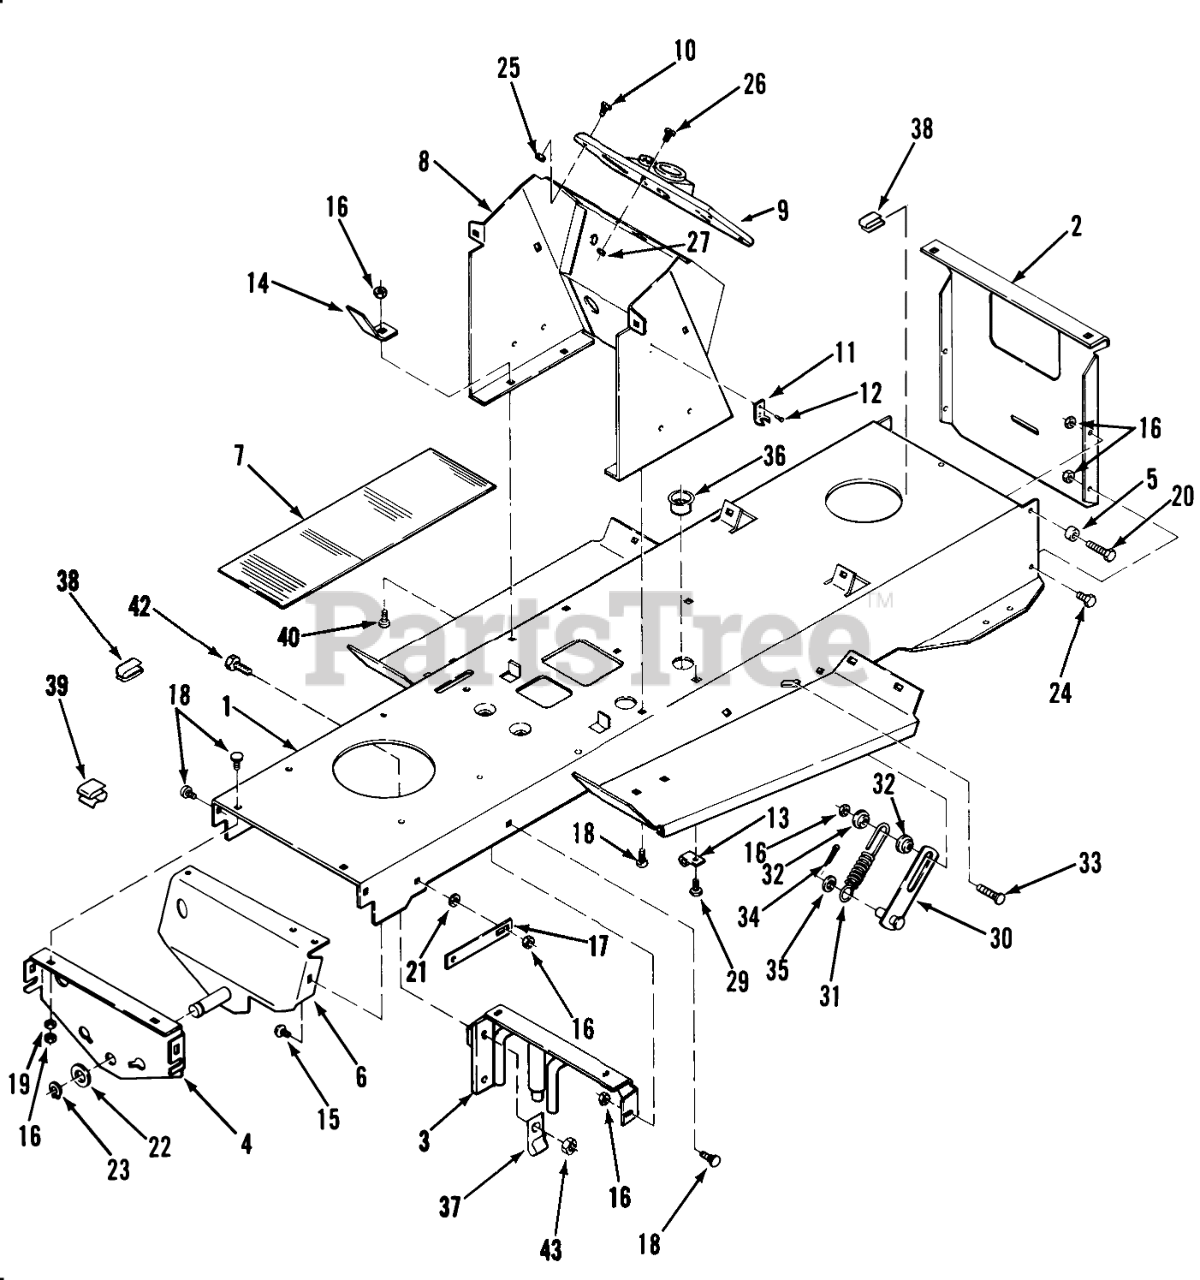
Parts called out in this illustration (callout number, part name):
1	Frame
2	PLATE DRAWBAR
3	ASS'Y-FRAME SUPPO R
4	PLATE SUPT - AXLE R
5	Spacer
6	ASS'Y-AXLE SPT RE R
7	PAD-FOOTREST
8	Hoodstand 208-4
8	Hoodstand 211-4
8	Hoodstand 212-6
9	CONSOLE
9	Console Panel 212-6
10	SCREW #10X.62 PHCR
11	Latch Keeper
12	RIVET
13	J-CLIP
14	BRACKET FUSE
15	Bolt-Carriage
16	Nut
17	STRAP R
18	Bolt
19	WASHER 5/16 SAE
20	Bolt
21	Washer-Lock
22	WASHER
22	WASHER-SHIM
23	Snap Ring
24	Bolt
25	Nut
26	Screw
27	Nut
29	Bolt
30	ASSY LINK B
31	SPRING
32	BUSHING
33	Bolt-Carriage
35	WASHER
36	BUSHING-NYLON 1.093
37	CLIP
38	RETAINER
39	CLIP-CABLE
40	Bolt
42	Bolt
43	NUT
